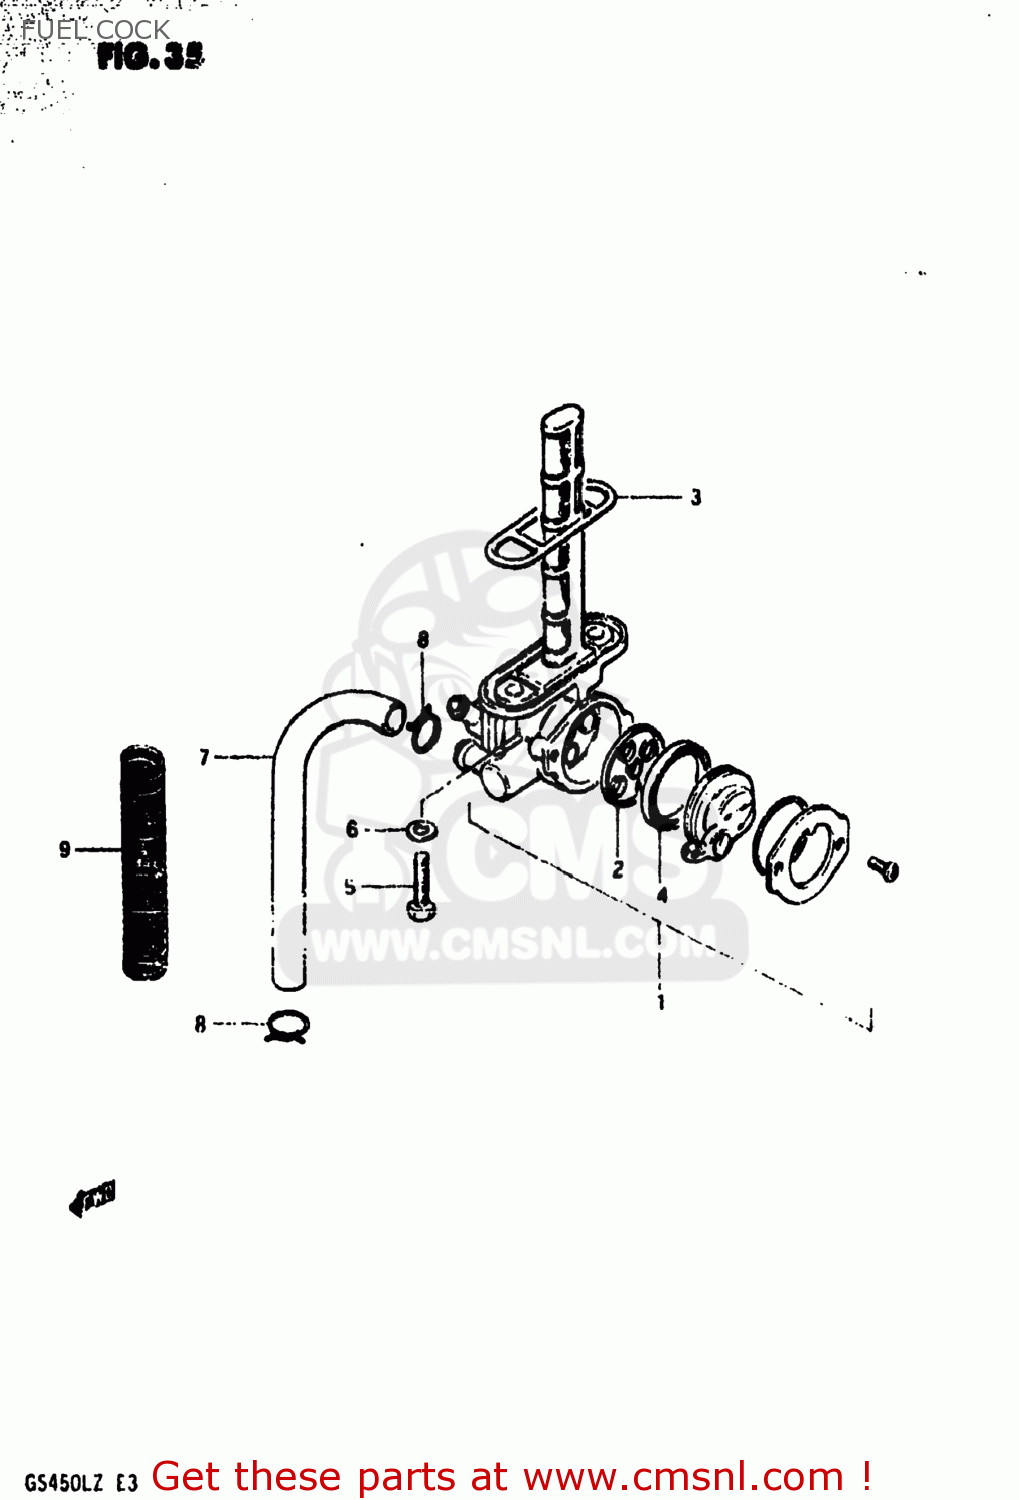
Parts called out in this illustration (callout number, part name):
1	COCK ASSY,FUEL
2	GASKET (NAS)
3	GASKET, FUEL COCK (NAS)
4	V SEAL,FUEL COCK
5	SCREW(6X30)
6	GASKET
7	HOSE
8	CLIP
9	SPRING
